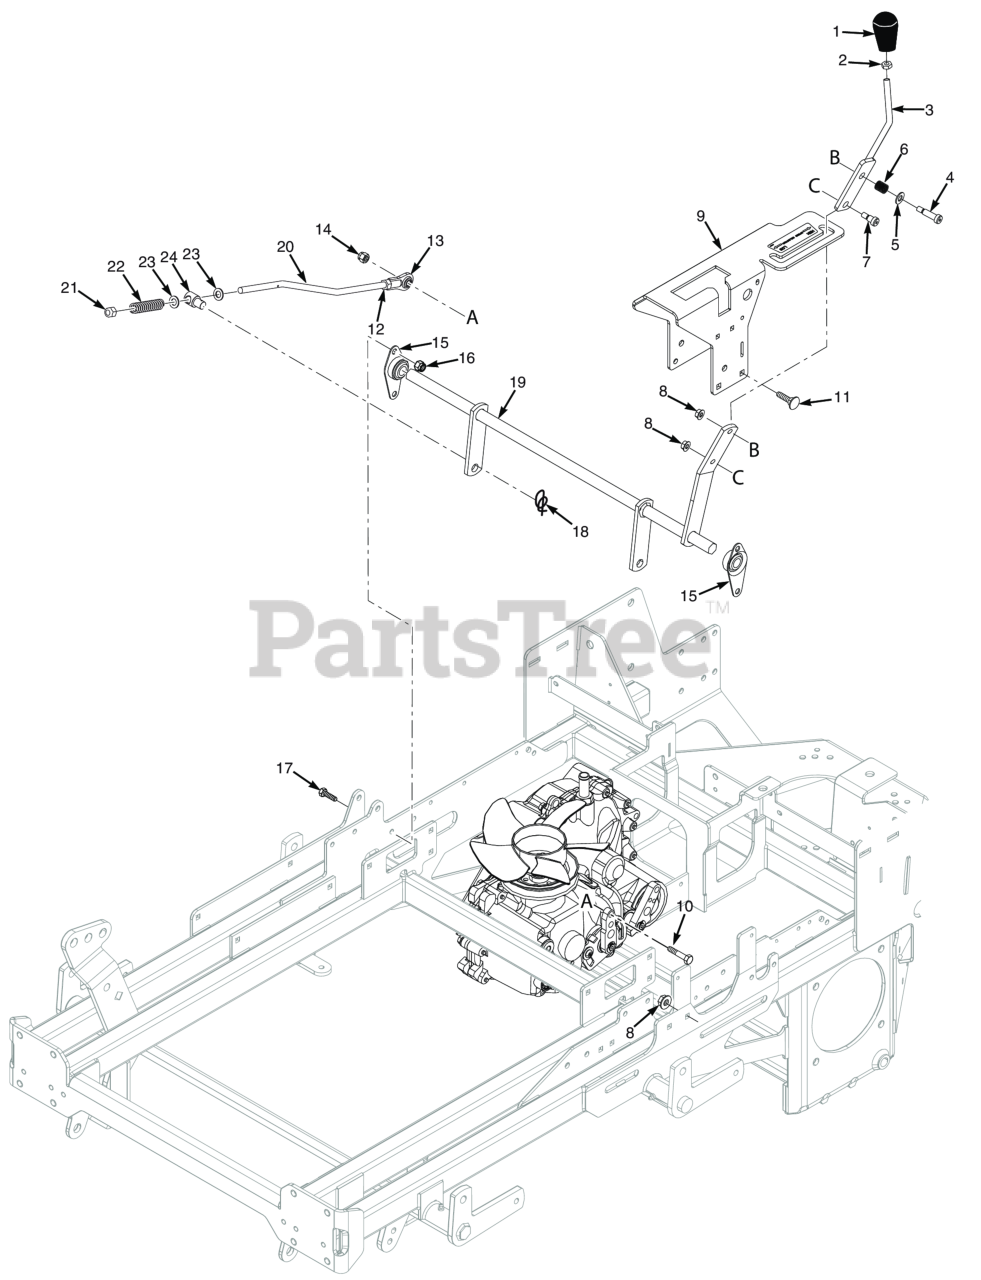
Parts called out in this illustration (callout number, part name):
1	Knob, Soft Touch
2	HEX NUT, JAM 3/8-16
3	Lever Weldment, Speed Control SCZII
4	Bolt, Shoulder 3/8 x 1"
5	Flatwasher, 3/8 (.406 x .812 x .065)
6	Spring, Speed Control Slide
7	Bolt, Shoulder 3/8 x .375"
8	Nut, Serrated Flange 5/16-18 (Right Front Engine Mounting, Briggs and Kohler Only)
9	Control Weldment w/ Decal
10	Bolt, 5/16 - 18 x 1 - 1/4" Hex Head
11	Bolt, 5/16-18 x .75 RHSN Carriage
12	HEX NUT, 3/8-24 R.H. THREAD
13	Rod End, 3/8-24
14	Nut, Center Lock, 5/16-18(32)
15	Bearing, Self Align
16	Nut, Flange Head Elastic Stop 5/16-18
17	BOLT, SERRATED FLANGE HEX HEAD 5/16-18 X 3/4"
18	Pin, Rue Cotter 1/2" Dia.
19	Speed Control Bellcrank Weldment
20	Speed Linkage Assembly (INCL. 12,13,21,22
21	Nut, Elastic Stop 3/8-24
22	Spring, Brake
23	FW, .375-.376/.380 X .734 X .063
24	BUSHING, PIVOT SLIDE
